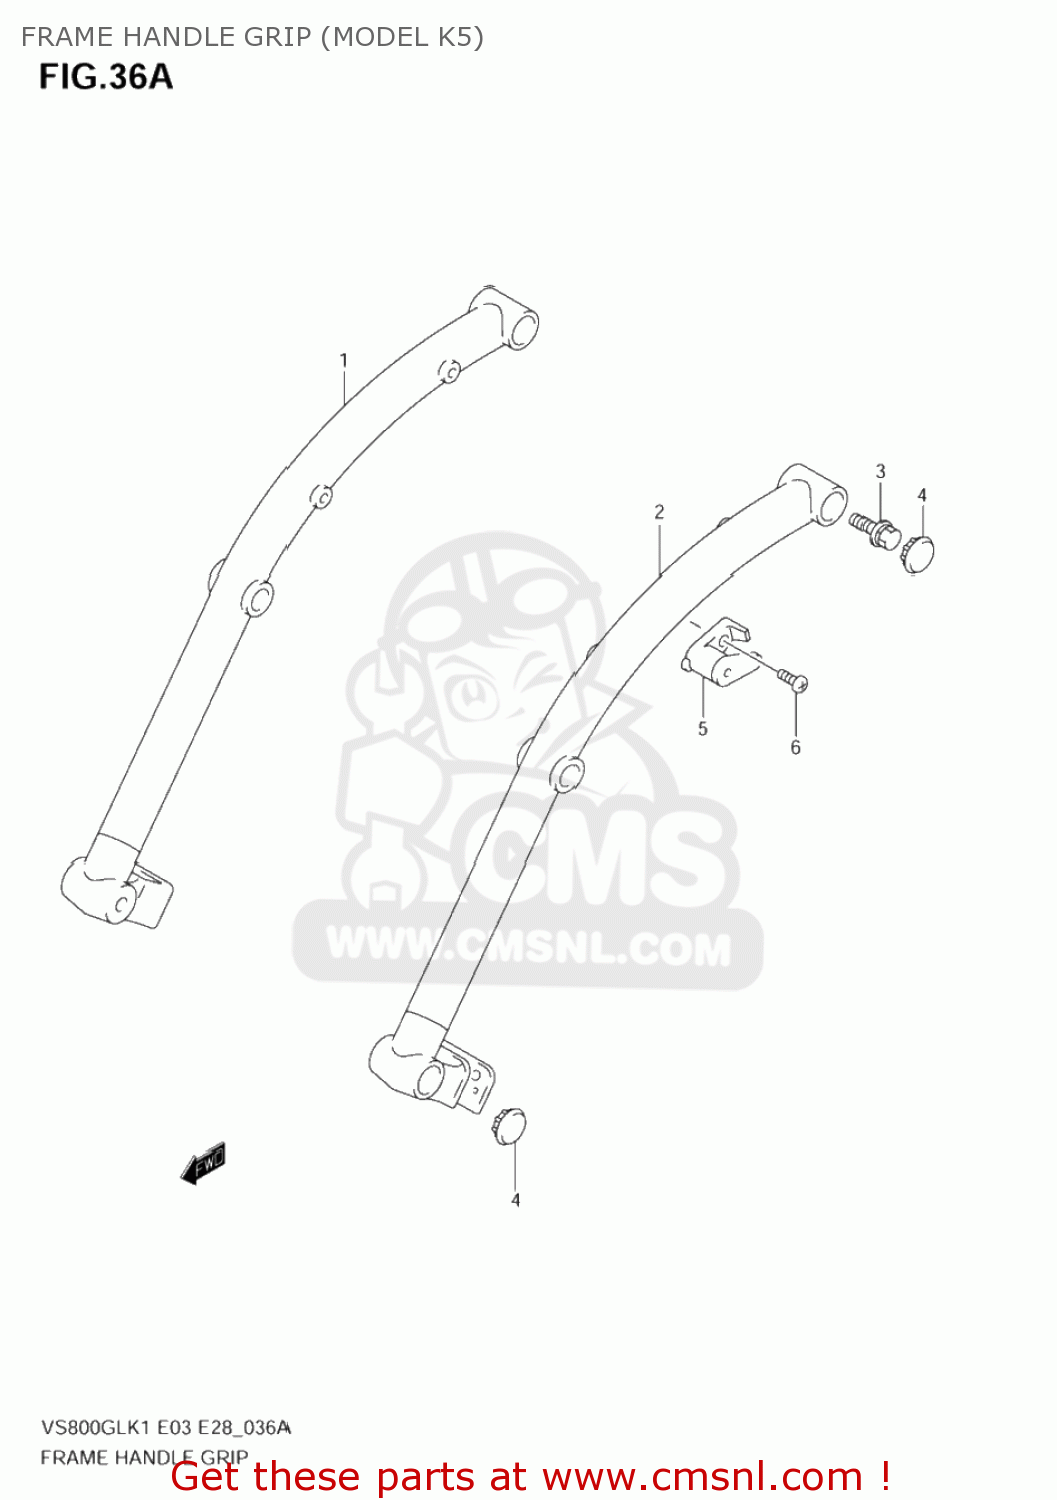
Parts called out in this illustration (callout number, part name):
1	GRIP,FRAME HANDLE RH
2	GRIP,FRAME HANDLE LH
3	BOLT
4	CAP,FRAME HANDLE GRIP
5	LOCK SET,HELMET
6	SCREW
